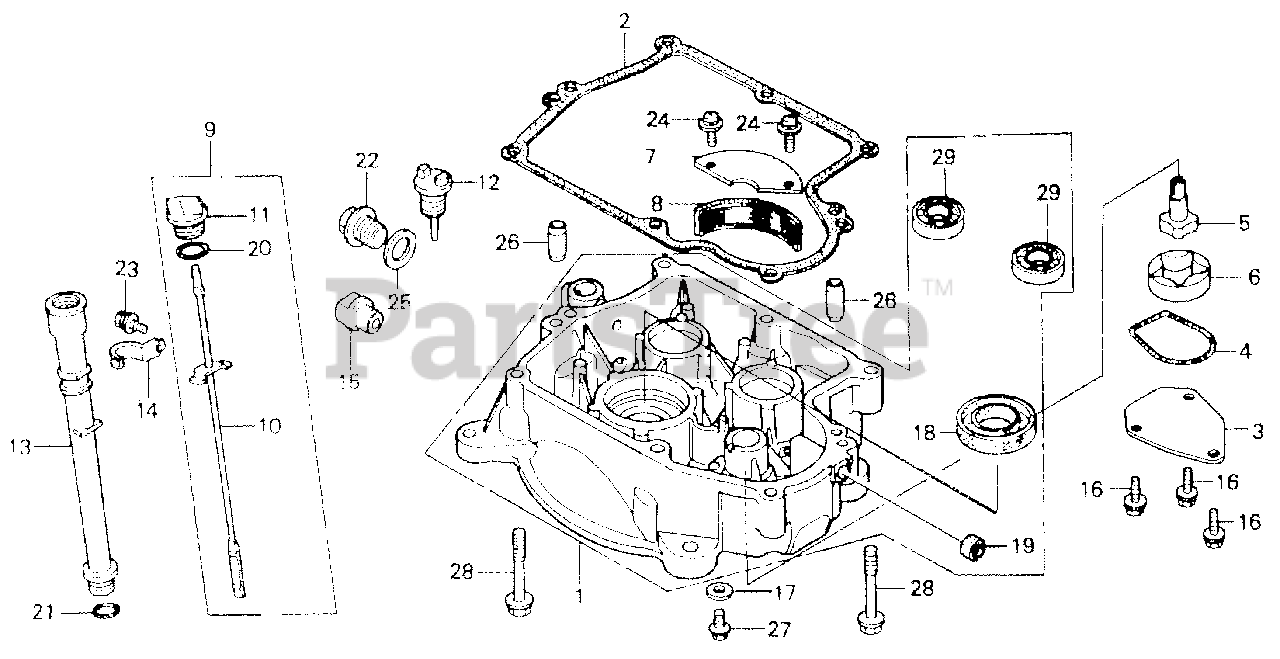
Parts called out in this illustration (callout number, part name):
1	PAN ASSY., OIL
2	GASKET, OIL PAN
3	COVER, OIL PUMP
4	O-RING (42X2.9)
5	ROTOR (INNER)
6	ROTOR, OIL PUMP (OUTER)
7	PLATE, OIL FILTER
8	SCREEN, OIL FILTER
9	GAUGE ASSY., OIL LEVEL
10	DIPSTICK, OIL
11	CAP, OIL
13	EXTENSION, OIL FILLER
14	CLAMP, EXTENSION
16	BOLT, FLANGE (6X12) (CT200)
17	WASHER A (8MM)
18	OIL SEAL (30X46X8)
19	OIL SEAL (6X11X4)
20	O-RING (26X2.7)
21	O-RING (16.8X2.4)
22	BOLT, DRAIN PLUG (20MM)
23	BOLT-WASHER (6X10)
24	SCREW-WASHER (5X12)
25	WASHER, DRAIN PLUG (20MM)
26	PIN A, DOWEL (8X14)
27	BOLT, FLANGE (8X16)
28	BOLT, FLANGE (8X45)
29	BEARING, RADIAL BALL (6203)
